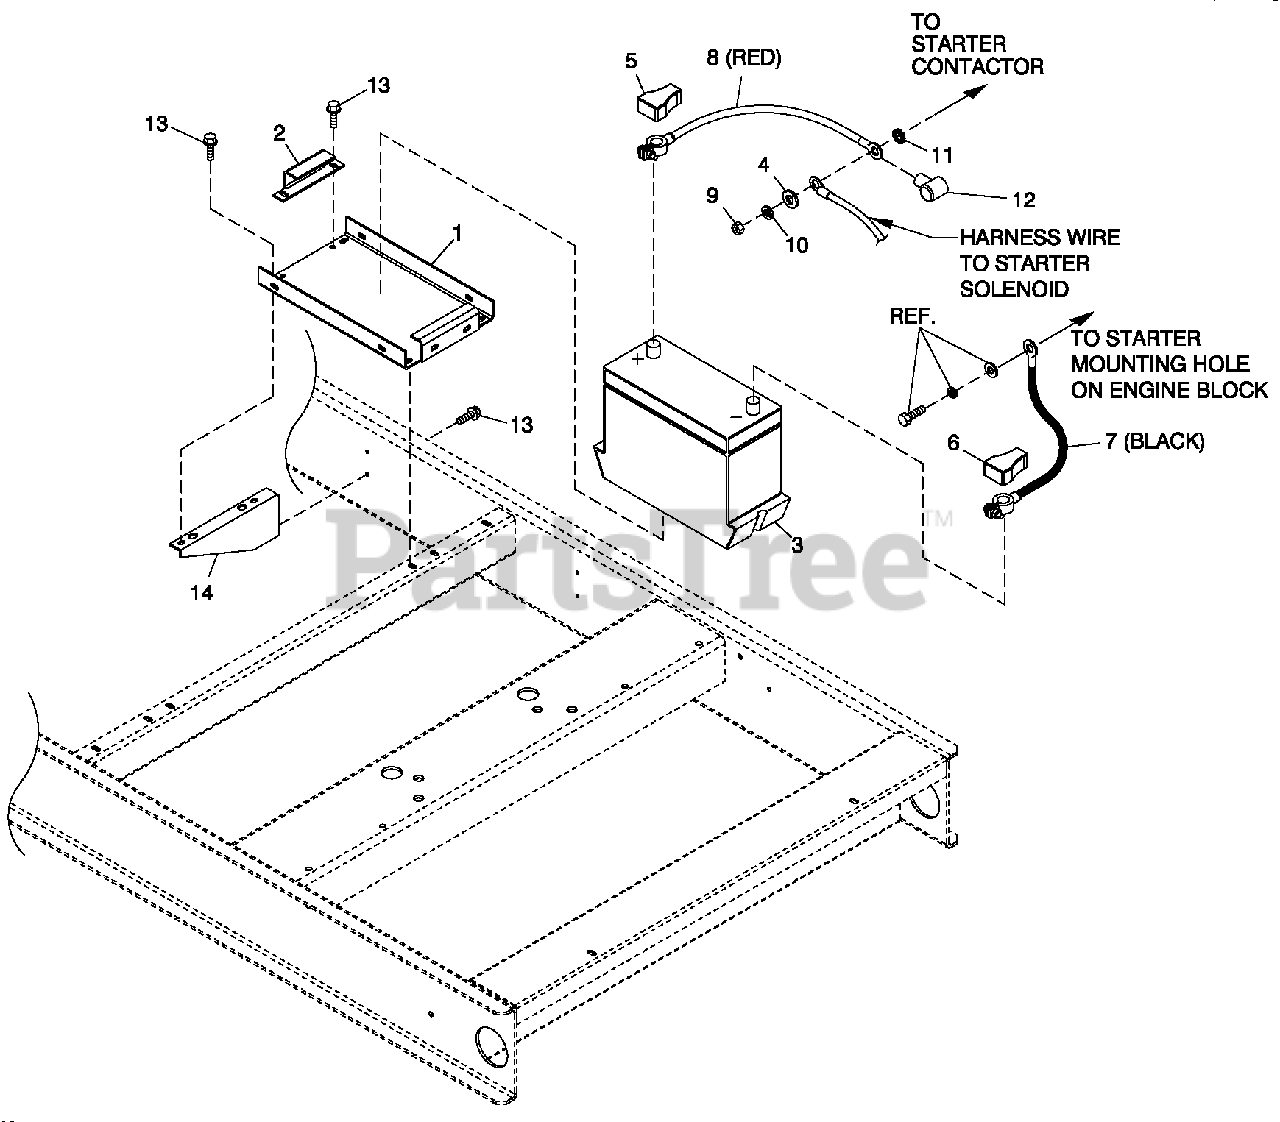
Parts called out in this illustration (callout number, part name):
1	TRAY BATTERY
2	STRAP BATTERY RETAINMENT
3	BATT12VDC 24F 625
4	WASHER FLAT 3/8-M10 ZINC
5	BATT POST COVER RED +
6	BATT POST COVER BLK -
7	CABLE BATT BLK #1X18.00
8	CABLE BATT RED #1X28.00
9	NUT HEX M8-1.25 G8 YEL CHR
10	WASHER LOCK M8-5/16
11	WASHER SHAKEPROOF EXT 5/16 STL
12	BOOT BATTERY CABLE
13	SCREW THF M6-1X16 N WA Z/JS
14	SUPPORT BATTERY TRAY
